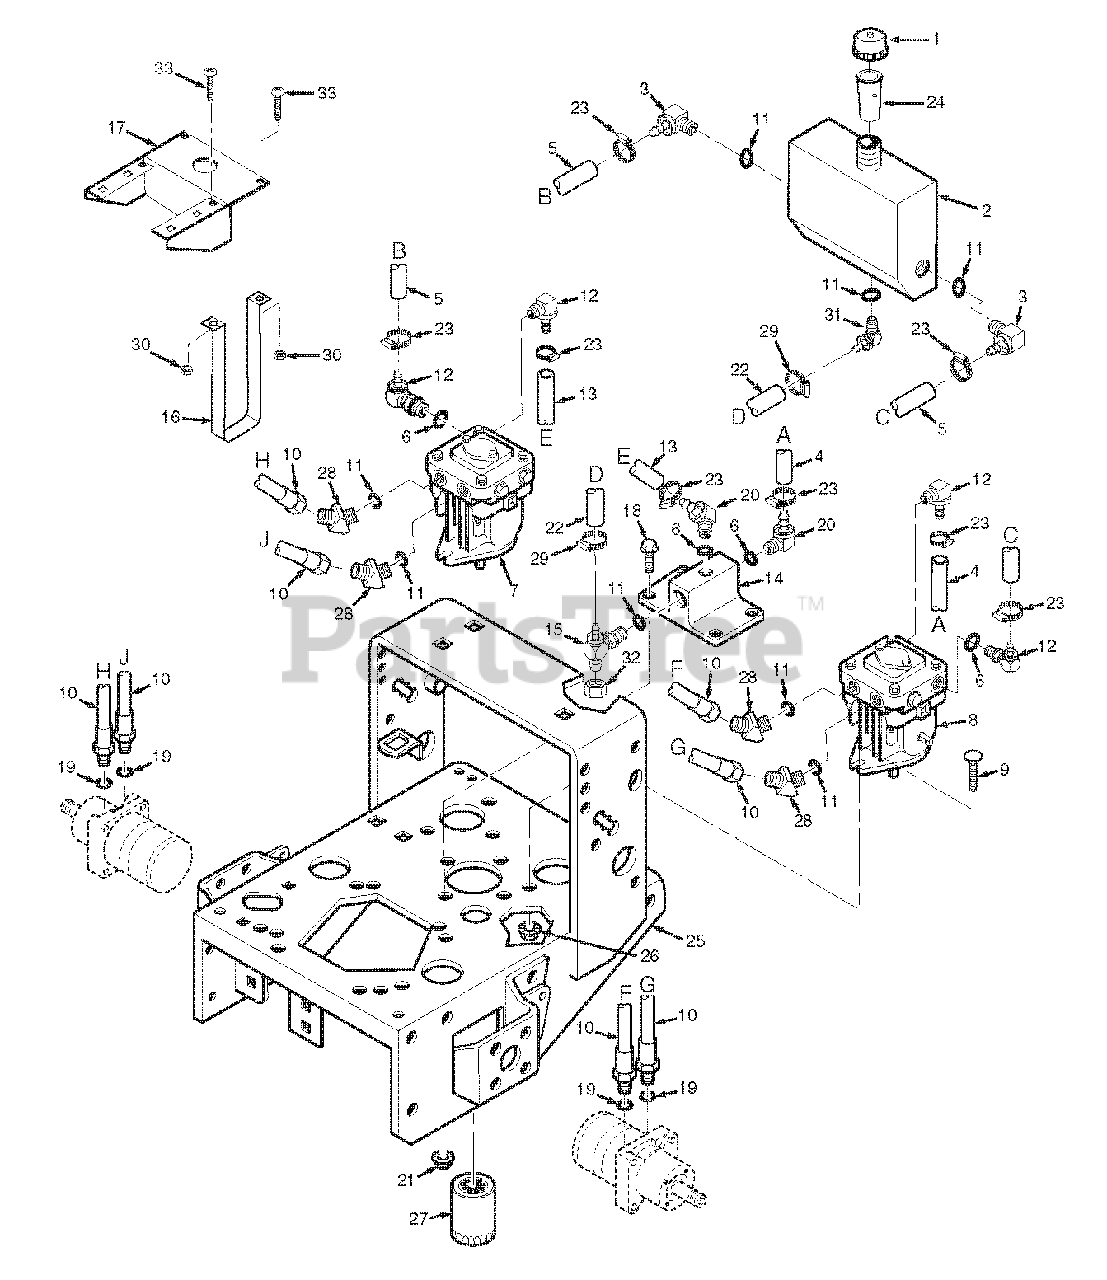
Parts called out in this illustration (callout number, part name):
1	Cap, Oil Reservoir
2	Oil Reservoir (With Fittings)
3	Elbow, 9/16 O-Ring x 3/8' Hose
4	Hose, 3/8' ID - 10-1/4' Long
5	Hose, 3/8' ID - 7' Long
6	O-Ring
7	Pump, PG-1JQQ-DY1X-XXXX (R.H.)
8	Pump, PG-1GQQ-DY1X-XXXX (L.H.)
9	Bolt, Carriage, 3/8-16 x 1.25'
10	Hose, Pump to Wheel Motor
11	O-Ring
12	Elbow, 7/16-20 O-Ring x 3/8' Hose
13	Hose, 3/8' ID - 11' Long
14	Oil Filter Base
15	Tee, 3/8 O-Ring x JIC x 1/2' Hose
16	Strap, Hydraulic Tank
17	Bracket, Hydraulic Tank
18	Capscrew, 5/16-18 x .75' Serr. Flange
19	O-Ring
20	Elbow, 9/16 O-Ring x 3/8' Hose
21	Nut, 5/16-18 Serr. Flange
22	Hose, Formed 1/2' ID
23	Clamp, .69 max dia.
24	Tube, Filler Neck
25	Engine Deck (16' Wide) with Decals - Small Frame
25	Engine Deck (20' Wide) with Decals - Large Frame
26	Nut, 3/8-16 Serr. Flange
27	Oil Filter
28	Elbow, 45 Deg.-3/4-16 JIC Male x Male 3/4-16 O-Ring
29	Clamp, .87 max di.
30	Nut, 1/4-20
31	Elbow, 3/4-16 O-Ring x 1/2' Hose
32	Cap, 3/4-16
33	Screw, 1/4-20 x 2.0' Round Head Phillips
